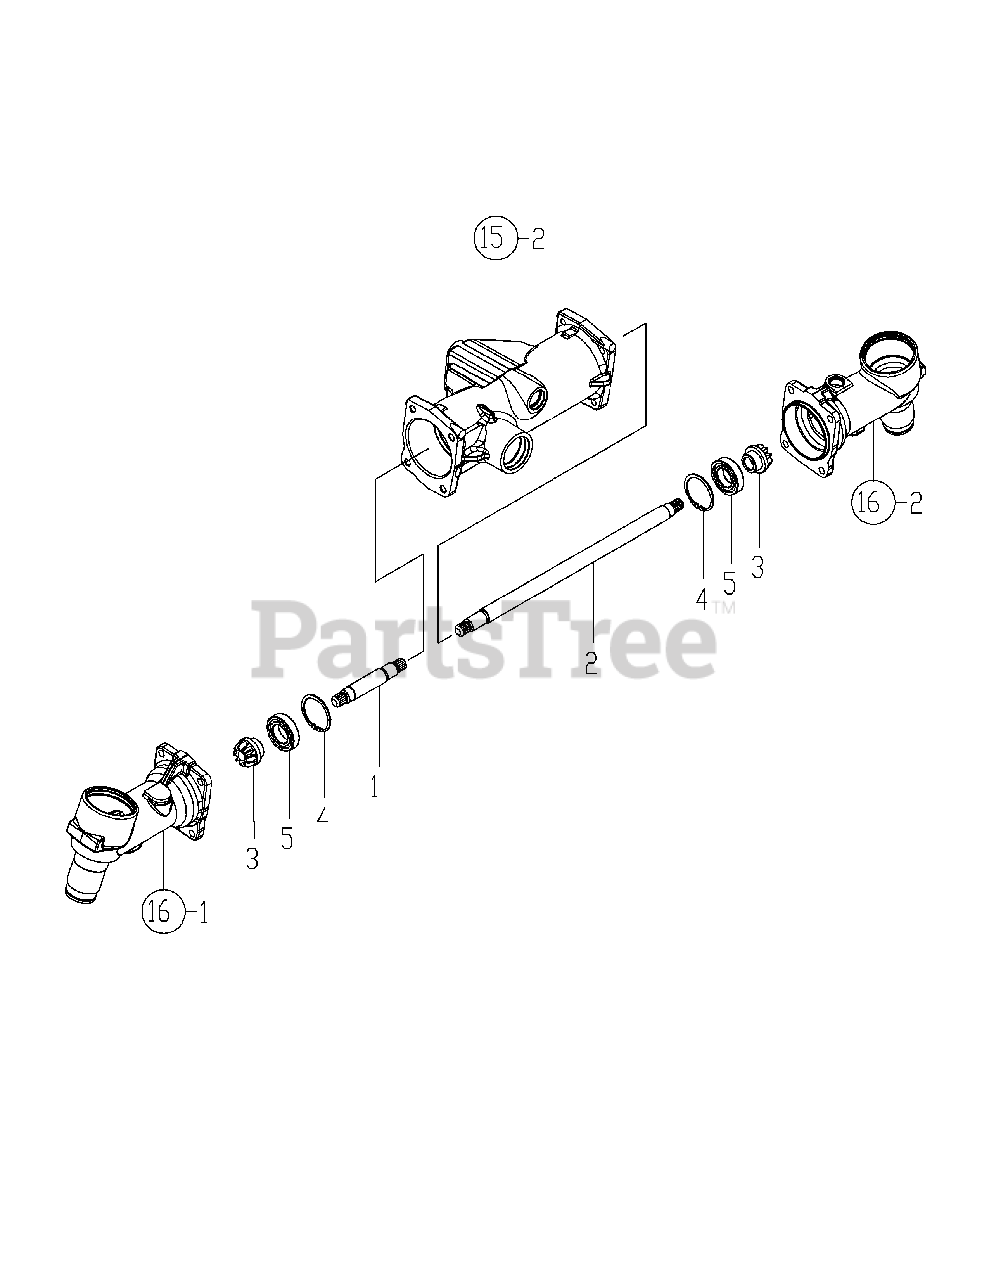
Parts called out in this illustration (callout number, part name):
1	SHAFT L,FRONT 1
2	SHAFT R,FRONT 1
5	BEARING, 6006 NTN
